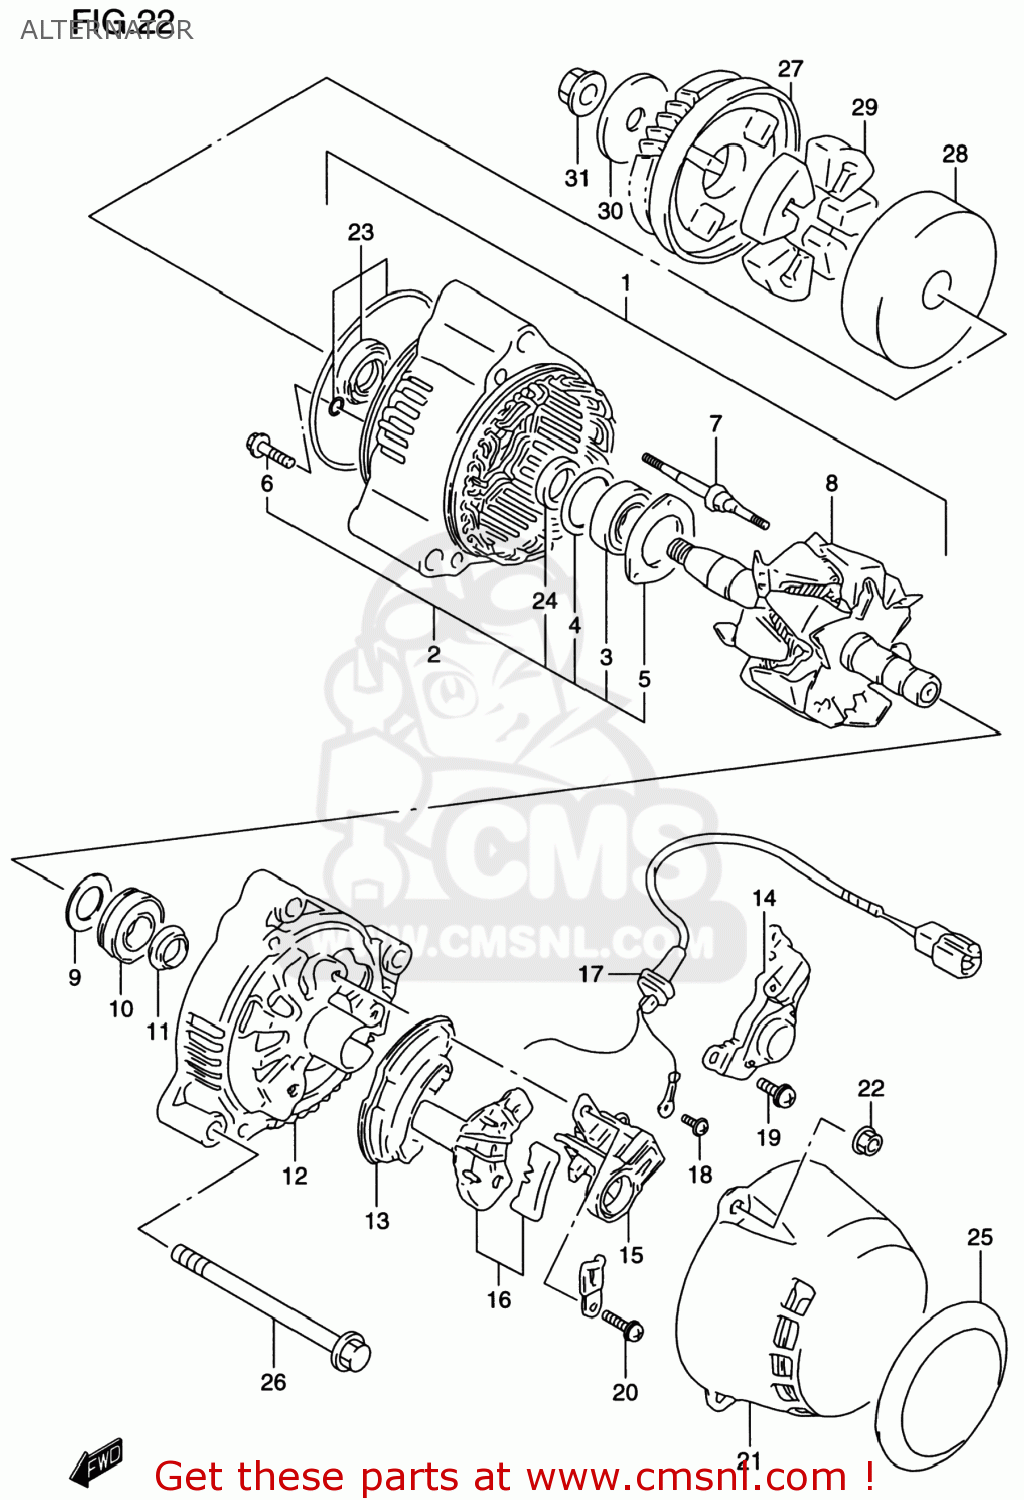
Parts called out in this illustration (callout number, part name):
1	ALTERNATOR ASSY
2	FRAME,DRIVE END
3	BEARING
4	COVER,BEARING
5	RETAINER
6	SCREW,BEARING RETAINER
7	STUD BOLT
8	ROTOR ASSY
9	COVER,BEARING
10	BEARING
11	COVER(2)
12	FRAME,END
13	HOLDER,RECTIFIER
14	REGULATOR
15	HOLDER,BRUSH
16	COVER,RECTIFIER
17	WIRE,LEAD
18	SCREW 4X6
19	SCREW
20	SCREW
21	COVER
22	NUT
23	SERVICE KIT(A)
24	SPACER
25	PLATE,ALTERNATOR ABSORBER
26	BOLT
27	GEAR,GENERATOR DRIVEN
28	HOUSING,GENERATOR GEAR DAMPER
29	DAMPER,GENERATOR DRIVEN
30	WASHER
31	NUT
